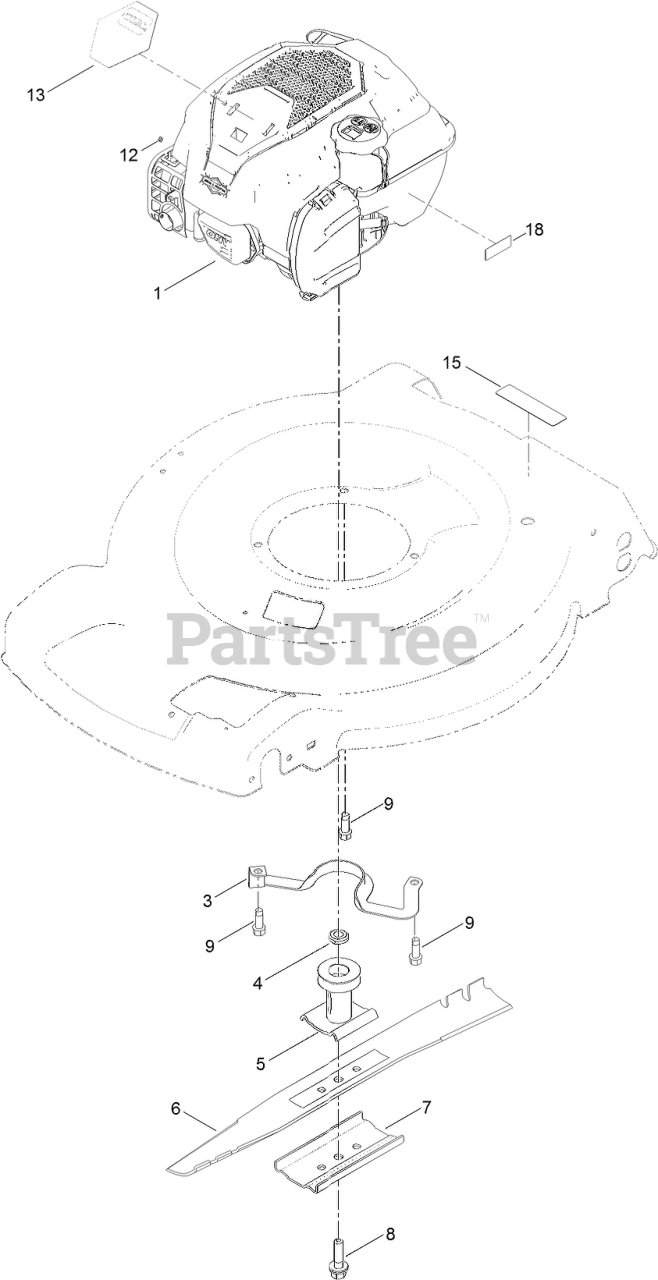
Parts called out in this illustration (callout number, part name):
3	Guide-Belt
4	Spacer-Driver
5	DRIVER-BLADE
6	BLADE-22 INCH
7	SUPPORT-BLADE
8	BOLT-BLADE
9	SCREW-TAPTITE
12	STOP-ROPE
13	DECAL-SHROUD
15	DECAL-ARRESTER, SPARK
18	DECAL-FUEL LEVEL
